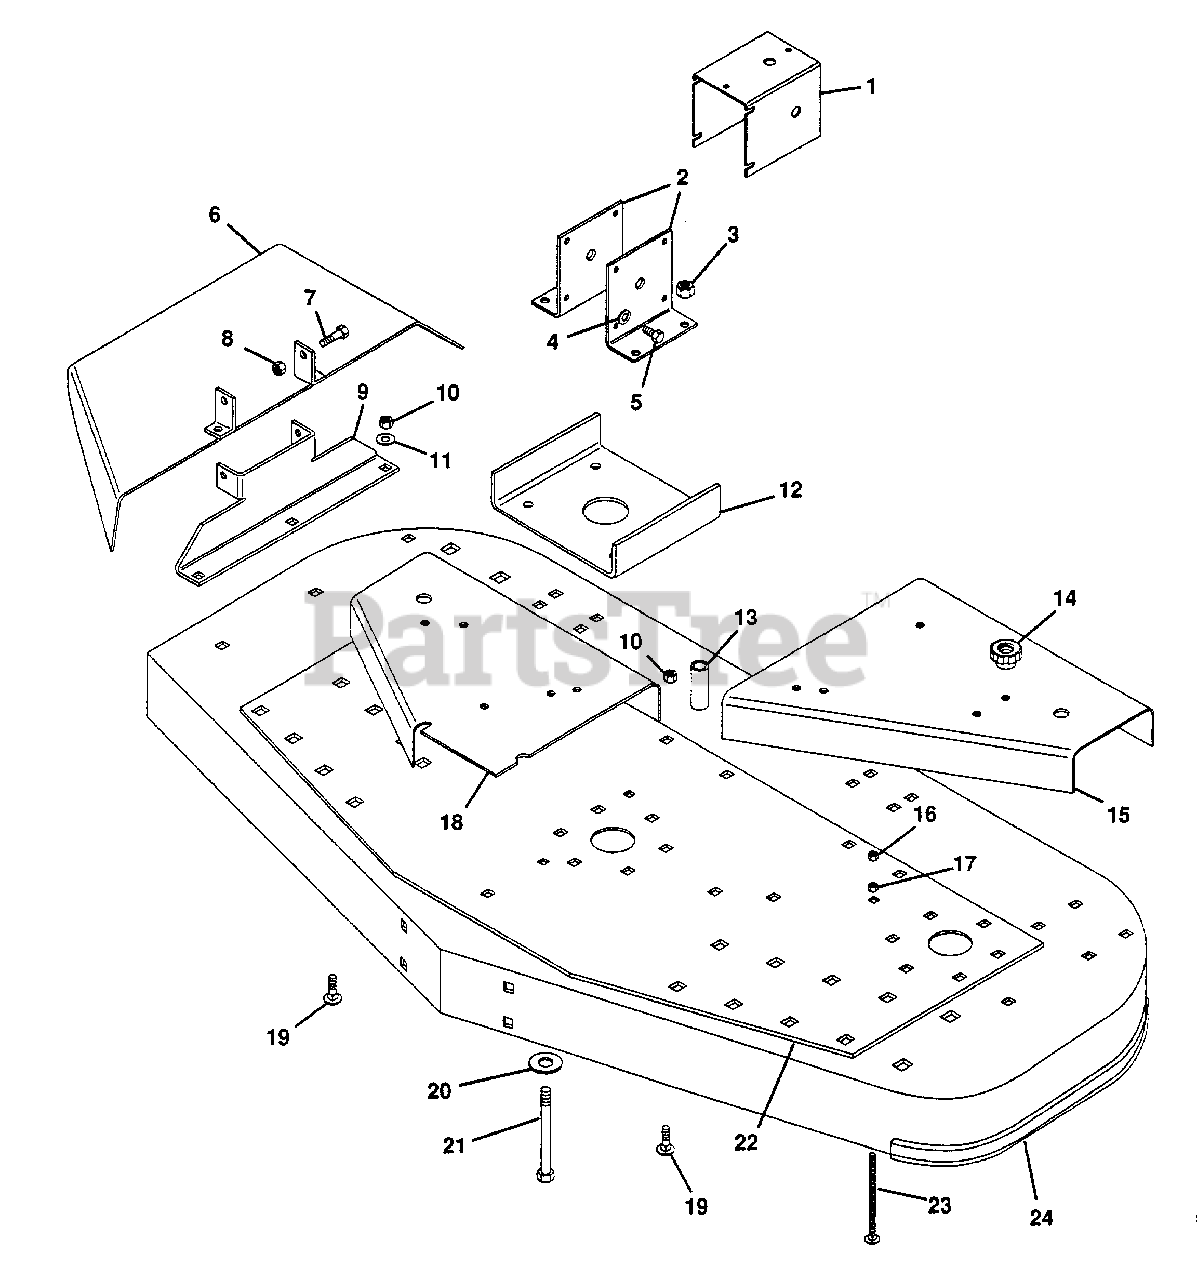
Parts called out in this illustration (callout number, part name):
1	Shield, U-Joint
2	Bracket, Gearbox Mounting
3	Nut, Lock 1/2-13
4	Washer, Lock 3/8 Reg.
5	Bolt, Hex 3/8-16x.875
6	Weldment, Discharge Chute
7	Bolt, Hex 1/4-20x.875
8	Nut, Lock 1/4-20
9	Bracket, Discharge
10	Nut, Lock 3/8-16
11	Washer, Flat .406x.812x.065
12	Plate, Support
13	Bushing, St. .532x1.0x2.00 Stl.
14	Knob
15	Cover, Belt Silkscreen
16	Nut, Lock 5/16-18
17	Nut, Jam 5/16-18 Hex
18	Cover, Belt R.H.
19	Bolt, 3/8-16x1.00 Rd Hd Sq Nk
20	Washer, Flat .531x1.062x.095
21	Bolt, Hex 1/2-13x3.75
22	Plate, Deck Support
23	Bolt, 5/16-16x4.0 Rd Hd Sq Nk
24	Weldment, 60" Mower Deck
